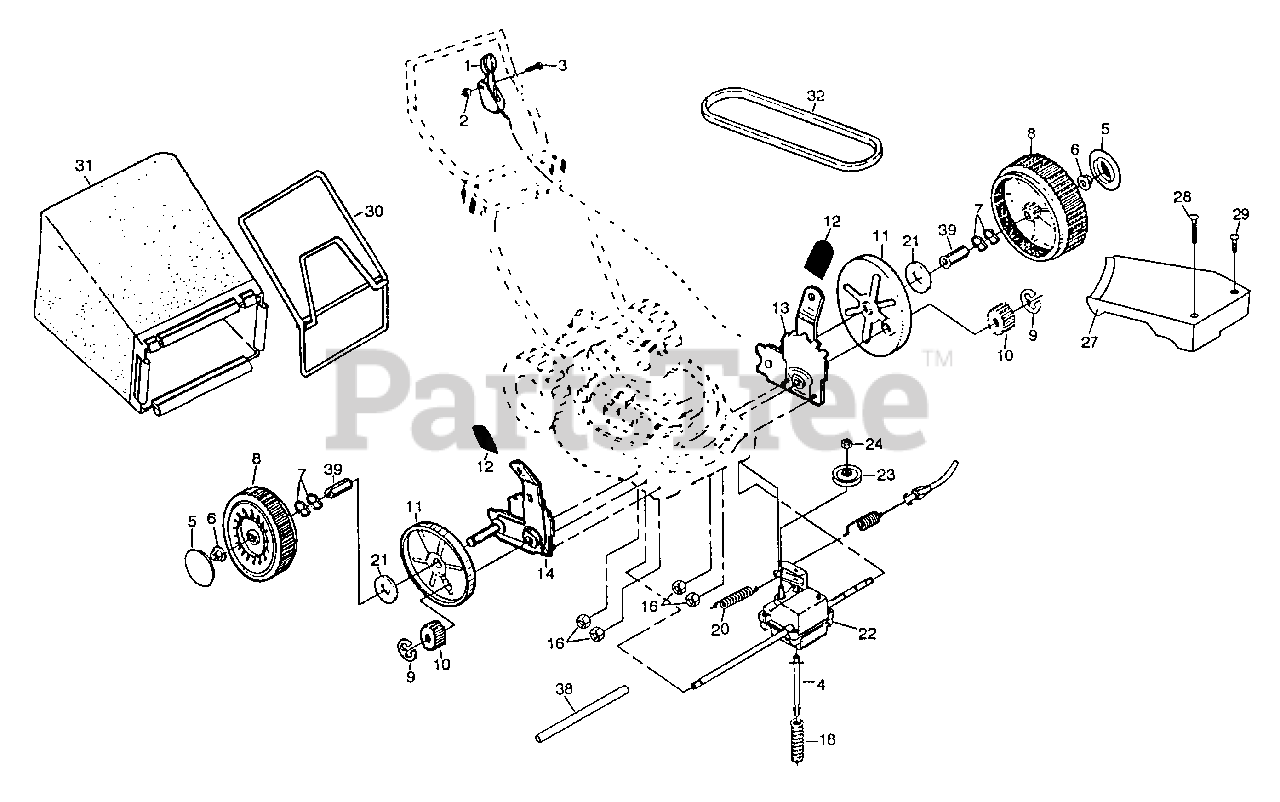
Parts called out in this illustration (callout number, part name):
1	Drive Control (AYP part number)
2	Locknut 1/4-20
3	Hex Washer Head Screw 1/4-20 x 2.12
4	Spring Retainer
5	Hubcap
6	Flanged Locknut
7	Wave Washer
8	Wheel & Tire Assembly (AYP part number)
9	E-ring
10	Pinion
11	Dust Cover
12	Selector Knob
13	Wheel Adjuster Assembly (Left)
14	Wheel Adjuster Assembly (Right)
16	Locknut
18	Spring
20	Spring
21	Washer 1/2 x 1-1/2 x .134
22	Gear Case Assembly (AYP part number)
23	Drive Pulley (AYP part number)
24	Locknut
27	Drive Cover
28	Pan Head Tapping Screw #10-24 x 2-3/4
29	Pan Head Tapping Screw #10-24 x 1-3/4
30	Catcher Frame
31	Grass Bag (AYP part number)
32	V-Belt (AYP part number)
38	Drive Shaft Cover
39	Wheel Bushing
